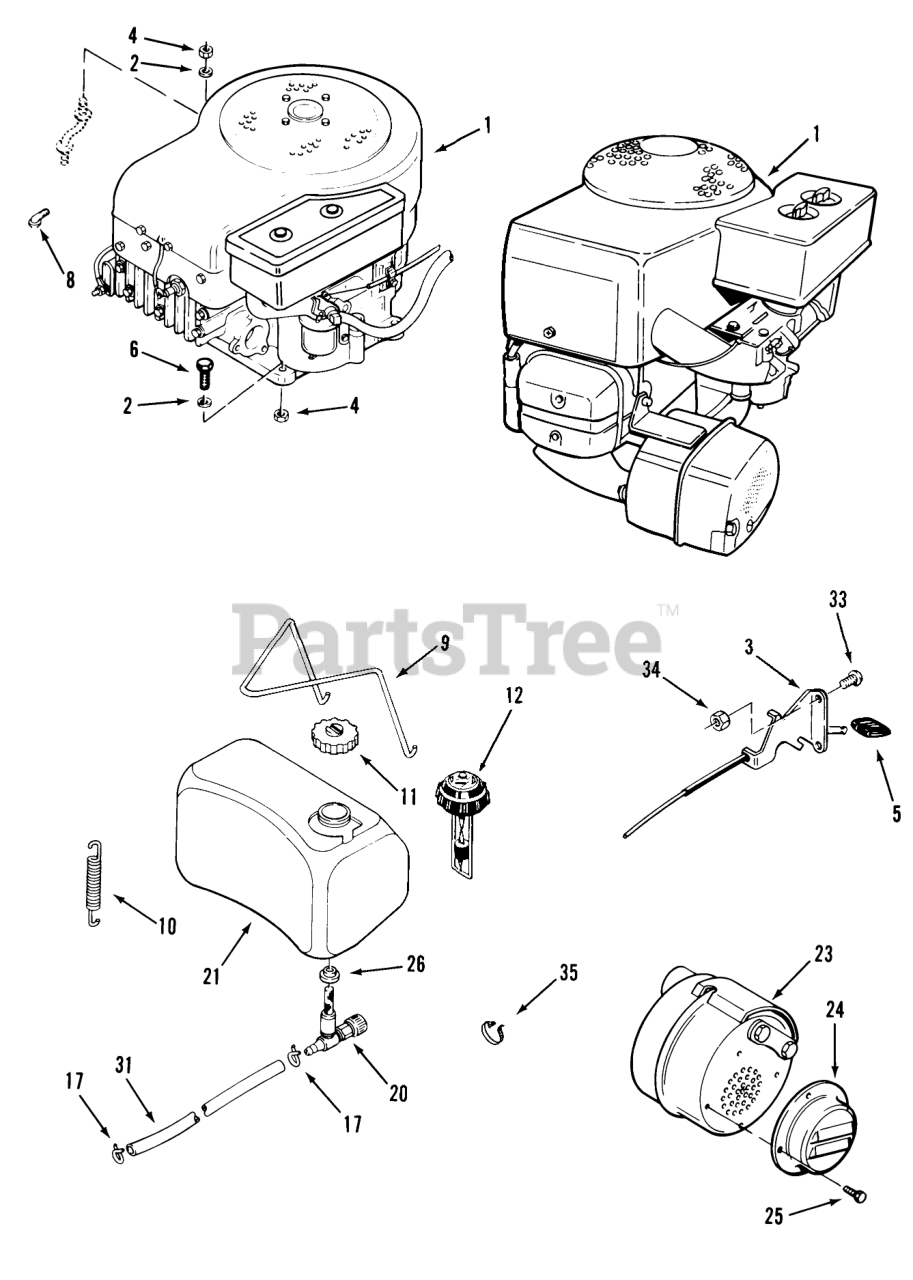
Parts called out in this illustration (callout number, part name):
1	Engine-08HP-B&S Model 191707, Type 2153-01 208-3 Only
2	WASHER 5/16 SAE
3	Choke/Throttle Control
4	Nut
5	KNOB-THROTTLE
6	Bolt
8	STREET ELBOW 45DEGRE
9	Hold Down Wire
10	SPRING-EXTENSION
11	CAP-GASOLINE
12	Gasoline Gauge Cap
17	Clamp
20	Fuel Valve
21	Fuel Tank Assy
23	MUFFLER
24	DEFLECTOR MUFFLER
25	Hex HD Screw 8-32 x 3/8-Black-211-3, 211-5
26	BUSHING
31	Fuel Hose 14.5 in. (36.8 cm) B-115 Only
33	Screw
34	Nut
35	Cable Tie
